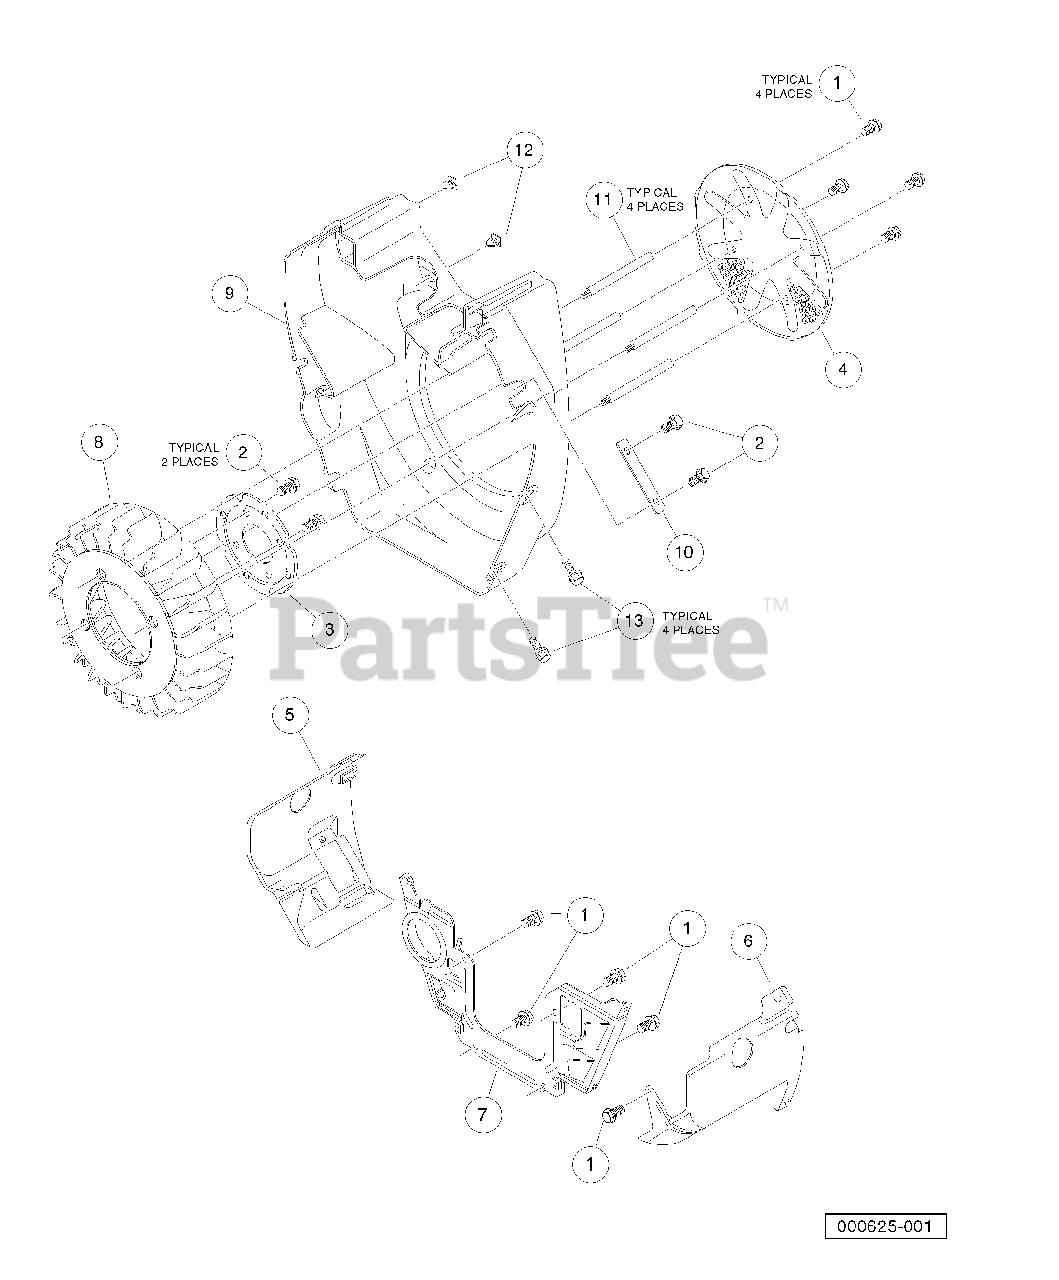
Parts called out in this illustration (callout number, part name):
1	Bolt, Flg, M6 X 1.0 X 12.
2	Bolt, Flg, M6 X 1.0 X 16
3	Plate, Housing, Fan, Fh
4	Screen, Fan, Fh
5	Shroud, Engine, Rh, Fh
6	Shroud, Engine, Lh, Fh
7	Shroud, Engine, Front, Fh
8	Fan, Cooling, Fh
9	Housing, Engine, Fh
10	Washer, Housing, Fan, Fh
11	Stud, Fan Screen, Fh
12	Nut, Press In, Front Cover, Fh
13	Bolt, Oil Pickup, Fh
